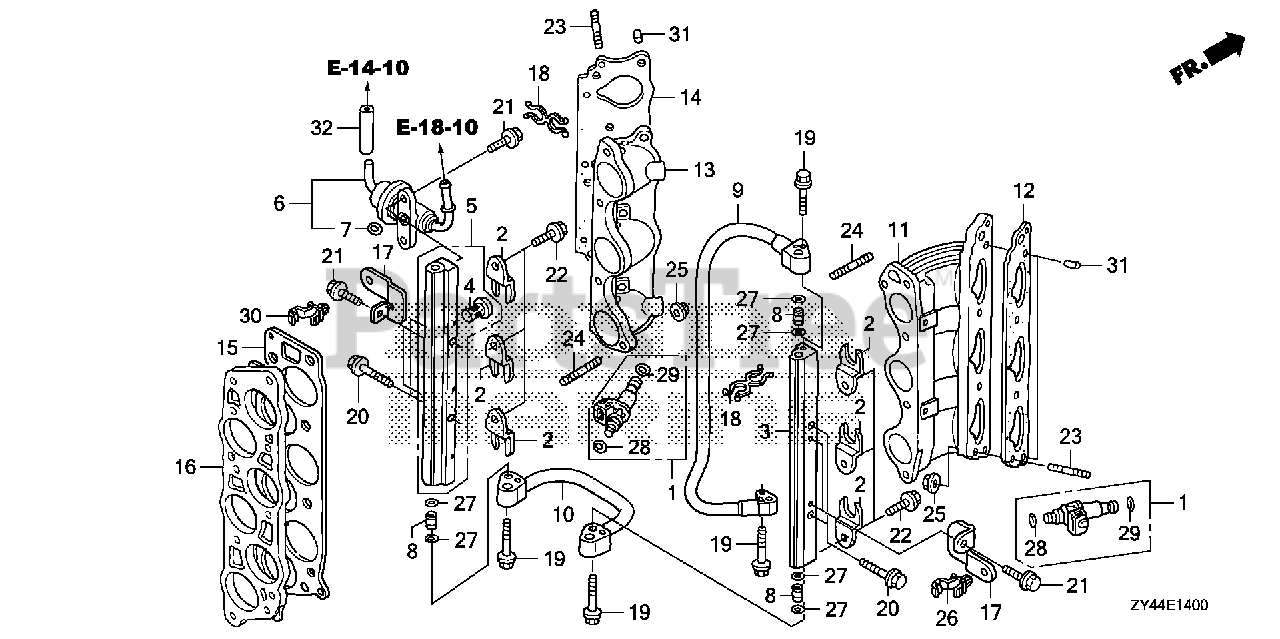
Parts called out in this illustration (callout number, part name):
1	INJECTOR ASSY., FUEL
2	CLIP, INJECTOR
3	PIPE, R. FUEL
4	MESH, FUEL FILTER
5	PIPE, L. FUEL
6	REGULATOR ASSY., PRESSURE
7	O-RING, PRESSURE REGULATOR
8	JOINT, FUEL PIPE
9	HOSE, FUEL
10	HOSE, FUEL JOINT
11	BASE, R. INJECTOR
12	GASKET, FR. INJECTOR BASE
13	BASE, L. INJECTOR
14	GASKET, RR. INJECTOR BASE
15	GASKET, IN. MANIFOLD
16	SPACER, IN. MANIFOLD
17	BRACKET, HARNESS CLIP A
18	CLIP D, SPEEDOMETER CABLE
19	BOLT, FLANGE (6X25)
20	BOLT, FLANGE (6X35)
21	BOLT, FLANGE (6X14)
22	BOLT, FLANGE (6X10)
23	BOLT, STUD (8X28)
24	BOLT, STUD (8X45)
25	NUT, FLANGE (8MM)
26	CLIP, WIRE HARNESS (10MM)
27	O-RING (7.8X1.9) (ARAI)
28	O-RING (7.47X3.6)
29	O-RING (7.45X3.61) (NOK)
30	CLIP, WIRE HARNESS (10MM)
31	PIN, DOWEL (10X12)
32	BULK HOSE, FUEL (3.5X3000) (3.5X50)
